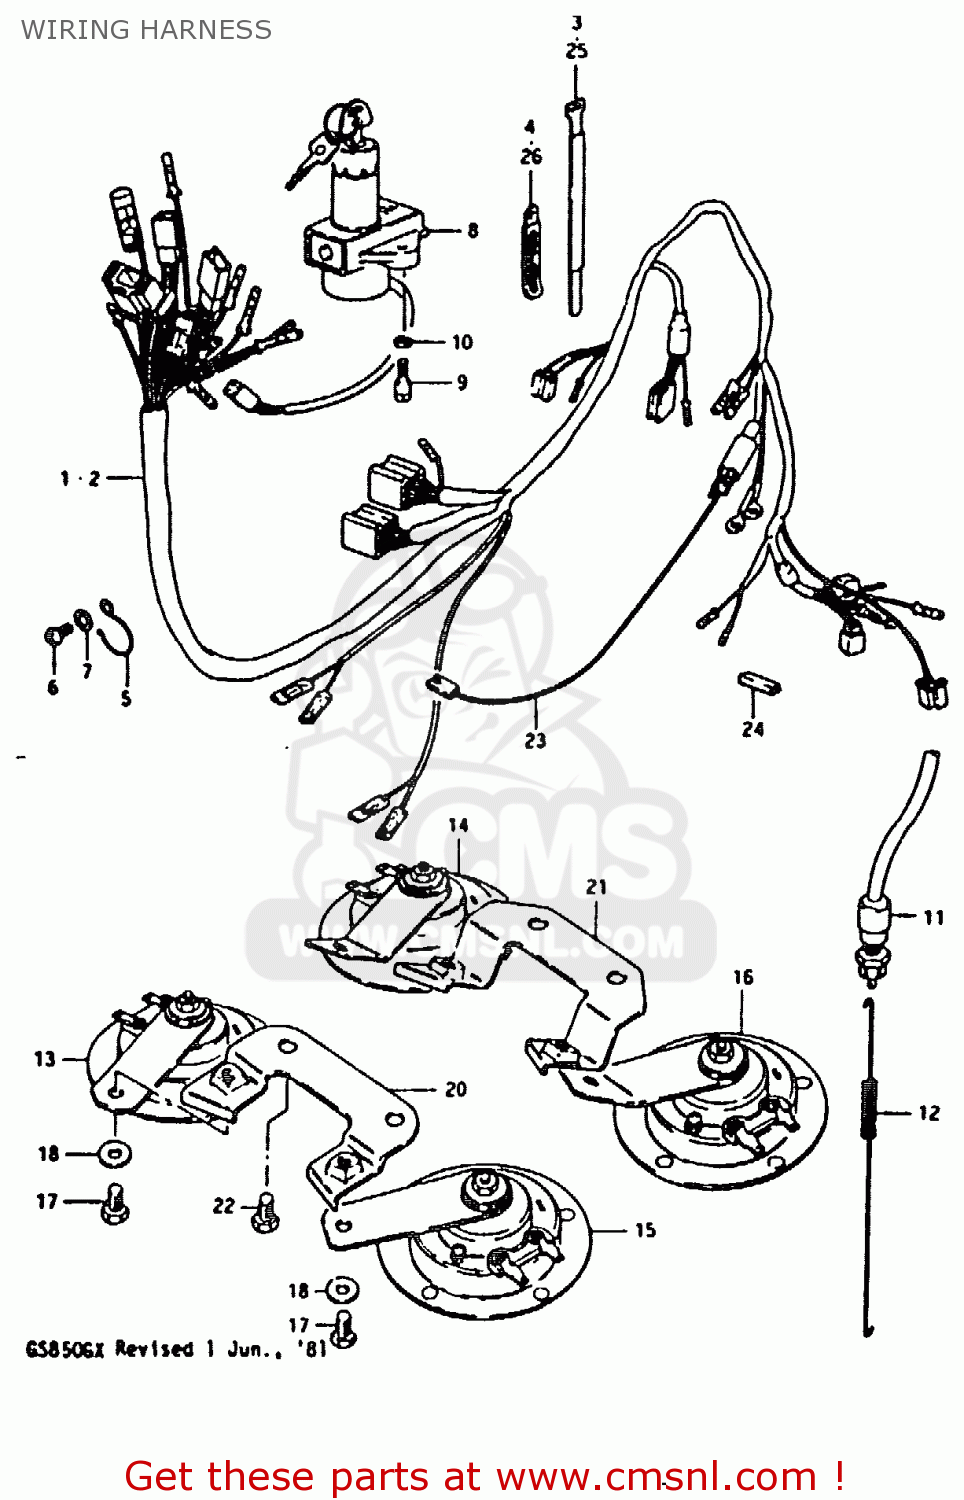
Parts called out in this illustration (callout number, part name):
1	HARNESS,WIRING
3	CLAMP
4	CLAMP
5	GUIDE,WIRING HARNESS
6	SCREW 6X12
7	WASHER
8	LOCK ASSEMBLY,STEERING
9	BOLT
10	LOCK WASHER
11	SWITCH ASSEMBLY,STOP LAMP
12	SPRING
13	HORN ASSEMBLY,LOW PITCH
14	HORN ASSEMBLY,LOW PITCH
15	HORN ASSEMBLY,HIGH PITCH
16	HORN ASSEMBLY,HIGH PITCH
17	BOLT
18	WASHER
19	BRACKET,HORN
20	BRACKET,HORN
21	BOLT 8X12
22	WIRE
23	PROTECTOR,WIRING HARNESS
24	CLAMP(L:120)
25	CLAMP
